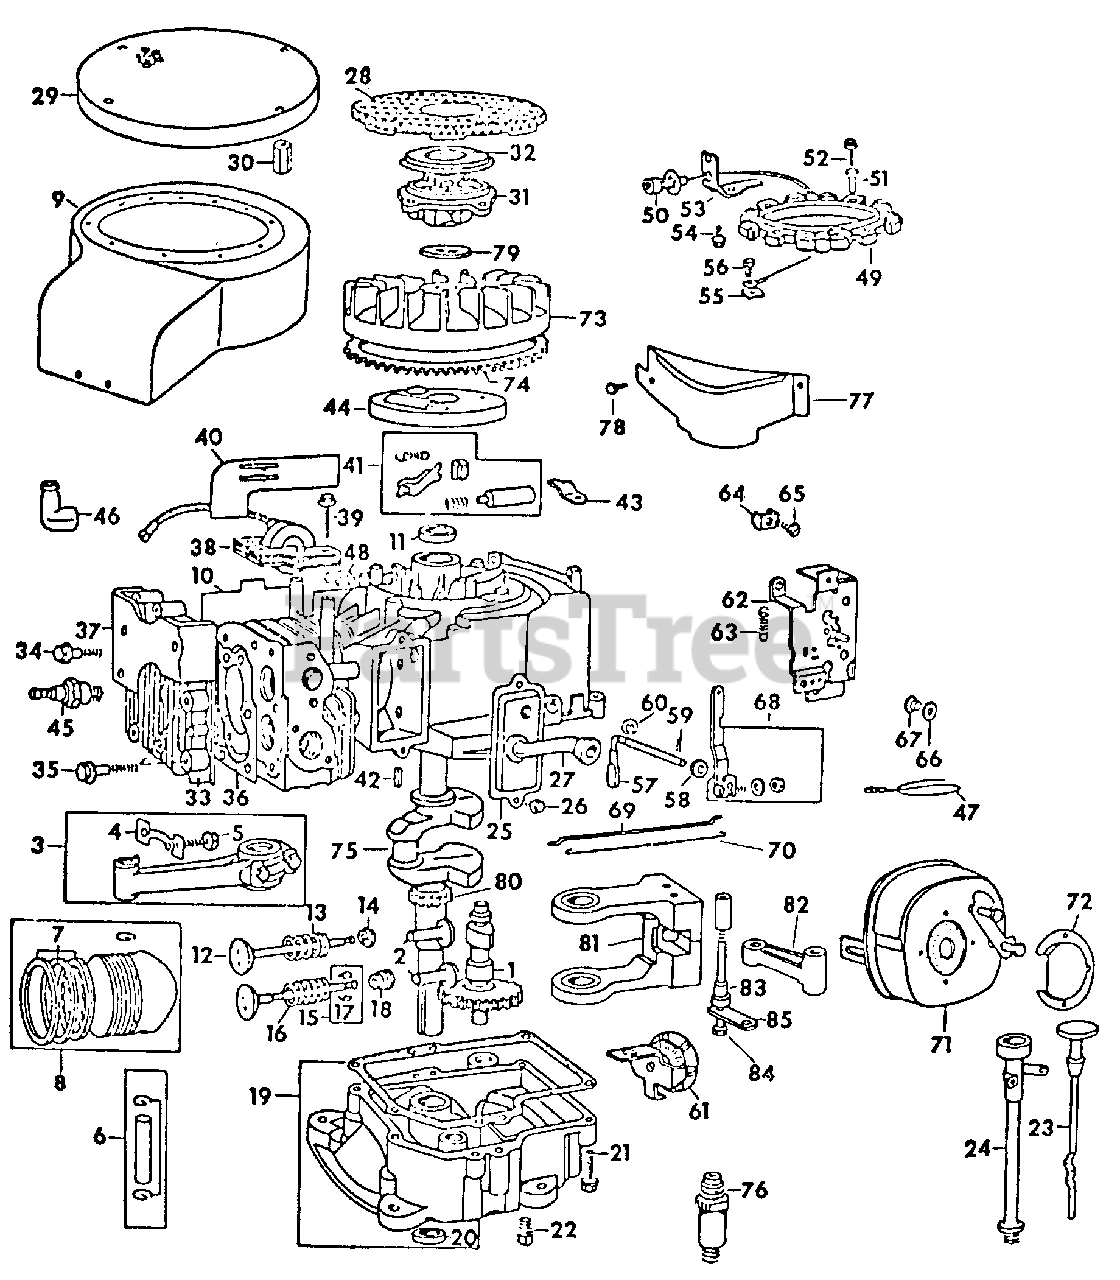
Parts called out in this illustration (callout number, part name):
1	Gear
2	Tappet, Valve
3	Rod Assy, Connecting, Std
4	Lock, Screw Head
5	Screw, Connecting Rod
6	Pin, Piston, Std
7	Ring Set, Piston Chrome, Std
8	Piston Assy, Std
9	Housing, Blower
10	Shield, Cylinder
12	Valve, Intake
13	Spring, Intake Valve
14	Retainer, Intake Valve
15	Valve w/Keepers, Exhaust
16	Spring, Exhaust Valve
17	Retainer, Roto-Coil
18	Roto-Coil, Exhaust Valve
20	Seal, Oil
21	Screw, Crankcase Cover Mounting
22	Plug, 3/8-18 Automotive Sq Hd Oil Drain
23	Not used in this application
24	Not used in this application
25	Breather, Valve Chamber
26	Screw, Breather Mounting
27	Tube, Breather
28	Screen, Rewind Starter
29	Screen, Blower Housing
30	Spacer, Blower Housing Screw
31	Housing, Rewind Starter (Clutch)
32	Cover, Housing
33	Head, Cylinder
34	Screw, Cylinder Head, Short
35	Screw, Cylinder Head, Long
36	Gasket, Cylinder Head
37	Cover, Cylinder Head
38	Armature Assy, Magneto
39	Screw, Armature Mounting
40	Guide, Air
41	Kit, Breaker Point & Condenser
42	Key, Flywheel
43	Clamp, Condenser
44	Cover, Breaker Point
45	Plug, Resistor Spark (Champion)
46	Elbow, Spark Plug Insulator
47	Wire Assy, Ground
49	Stator w/Bracket, Alternator
51	Bushing, Stator
52	Screw, Stator Mounting
53	Bracket, Fuse
54	Screw, Bracket Mounting
56	Screw, 8-32 X 3/8 Hex Hd
57	Crank, Governor
58	Washer, Governor Crank
59	Cotter, Governor Crank
60	Retainer, Governor Crank
61	Gear, Governor
62	Plate, Governor
63	Spring, Governor
64	Clamp, Casing
65	Screw w/Lock Washer, Hex Hd
66	Washer, Insulating
67	Collar, Insulating
68	Lever Assy, Governor
69	Link, Governor
70	Spring, Governor Link
71	Muffler
72	Deflector
73	Flywheel
74	Gear, Flywheel Ring
75	Crankshaft
76	Plug, Oil Minder
77	Guard, Ring Gear
78	Screw, Guard Mounting
79	Washer, Spring
80	Gear, Timing
81	Counterweight
82	Link, Counterweight
83	Spacer, Counterweight
84	Bolt, Counterweight
85	Shim, Screw Head Lock
